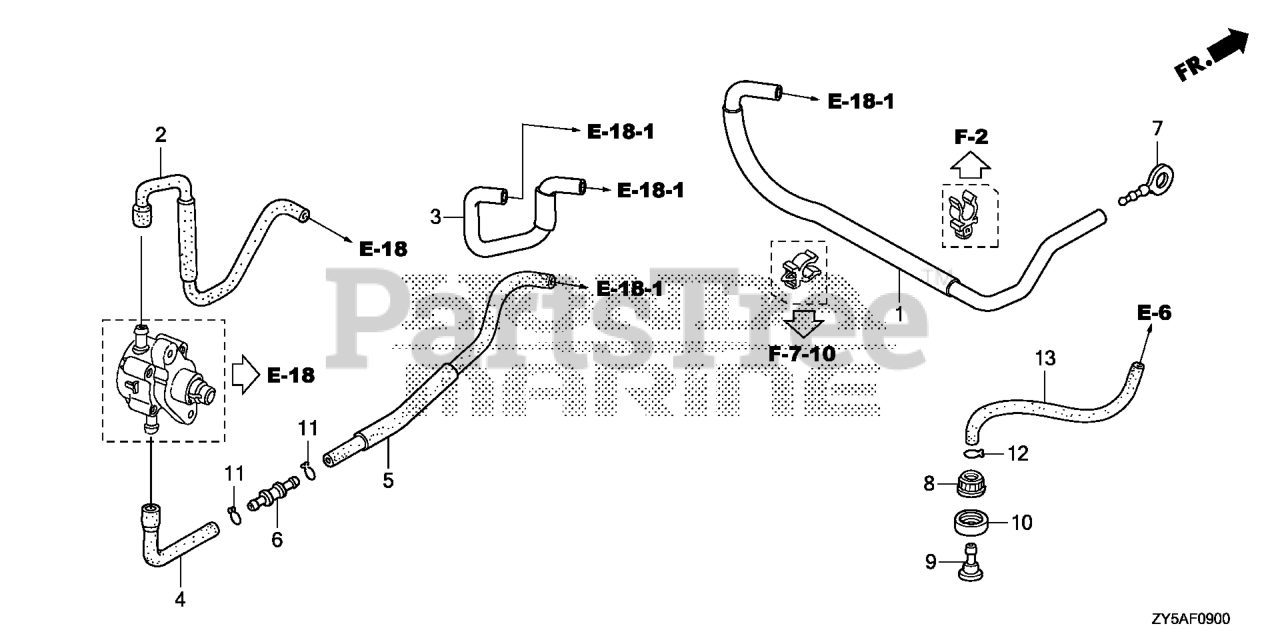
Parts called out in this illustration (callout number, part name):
1	TUBE A, FUEL (FKM)
2	TUBE B, FUEL
3	TUBE C, FUEL
4	TUBE D, FUEL
5	TUBE E, FUEL
6	JOINT, FUEL TUBE
7	PLUG, FUEL TUBE
8	NUT, WATER MOUTH
9	JOINT, WATER HOSE
10	SEAT, WATER MOUTH
11	CLIP, TUBE (B12)
12	CLIP B1, TUBE
13	BULK HOSE, FUEL (8X1000) (95001-80001-(95001-80001-60M)
